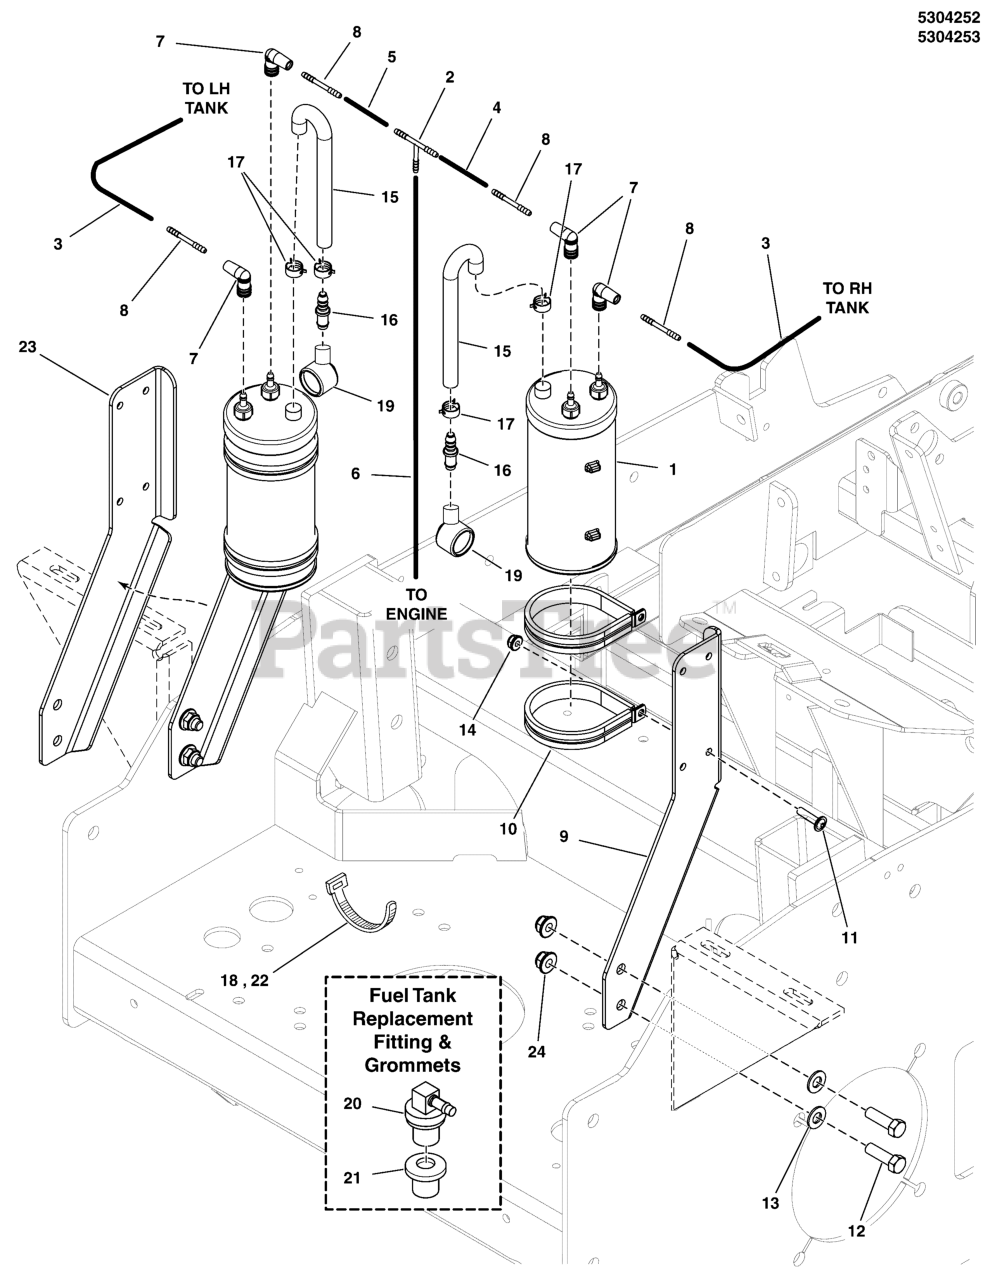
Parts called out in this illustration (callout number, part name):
1	CNSTR, CARB, 6 GAL
2	FITTING, 3/16" TEE, BARB TYPE, HDPE
3	HOSE, VAPOR, 5MM ID, 7.50 LG
4	HOSE, VAPOR, 5MM ID, 40.00 LG
5	HOSE, VAPOR, 5MM ID, 16.50 LG
6	HOSE, VAPOR, 5MM ID, 22.00 LG
7	FITTING, 90 DEG, 3/16X3/16, SANTOPRENE
8	FITTING, STRAIGHT, 3/16X3/16, PLASTIC
9	BRACKET, EVAP MOUNT, RIGHT - BLK
10	CLAMP, 3" ID, CUSHIONED, STAINLESS
12	BOLT, 3/8-16 X 1-1/4" GD5 CZ
13	WASHER, 3/8 SAE
14	NUT, 1/4-20 HEX NYLOCK FLANGE
15	HOSE, FORMED, EVAP CANISTER
16	FITTING, STRAIGHT, 10MMX10MM, PLASTIC
17	CLAMP, HOSE
18	TIE, SELF-LOCKING, 15"
19	DUST FILTER, CANISTER (SV)
20	REMOTE VENT ASSEMBLY
21	GROMMET (SV)
22	TIE, SELF-LOCKING, 12"
23	BRACKET, EVAP MOUNT, LEFT - BLK
24	NUT, 3/8-16 HEX NYLOCK FLANGE
